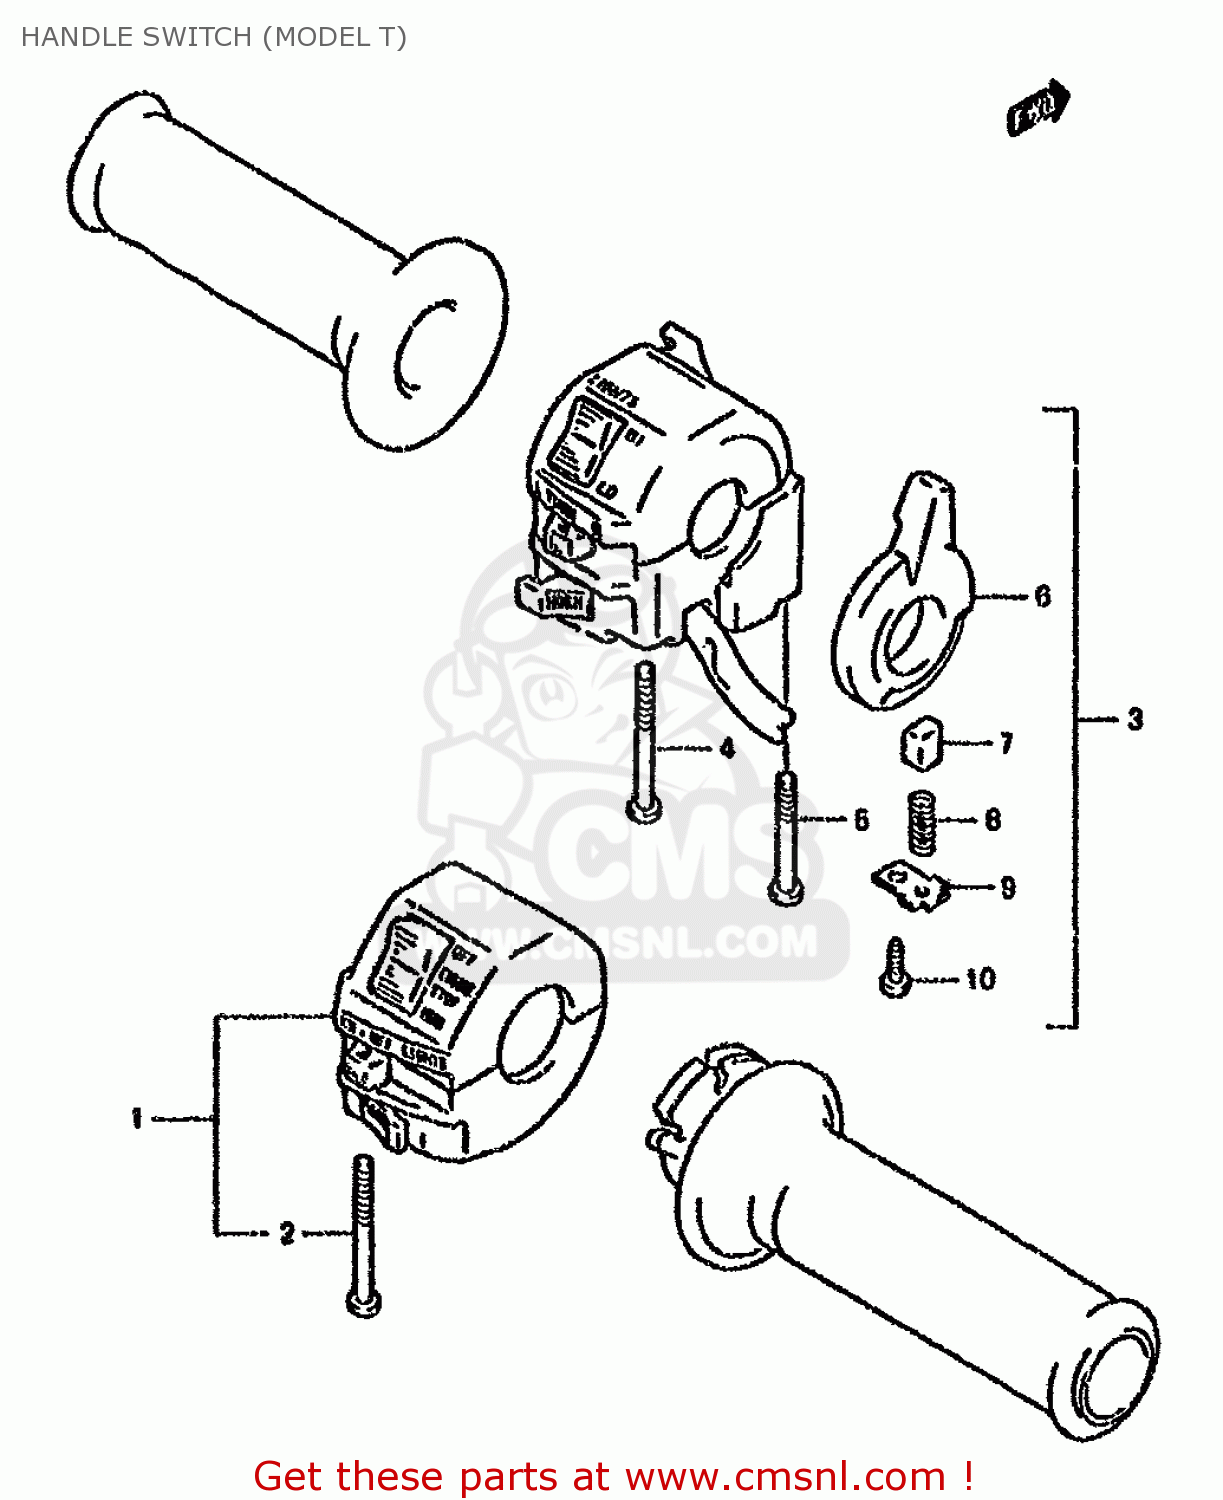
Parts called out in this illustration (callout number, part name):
1	SWITCH ASSY,HA
2	SCREW, 5X45
3	SWITCH ASSY
4	SCREW, 5X45
5	SCREW
6	LEVER,CHOKE
7	PIECE,SLIDE
8	SPRING
9	PLATE
10	SCREW, TRUNK BOX
